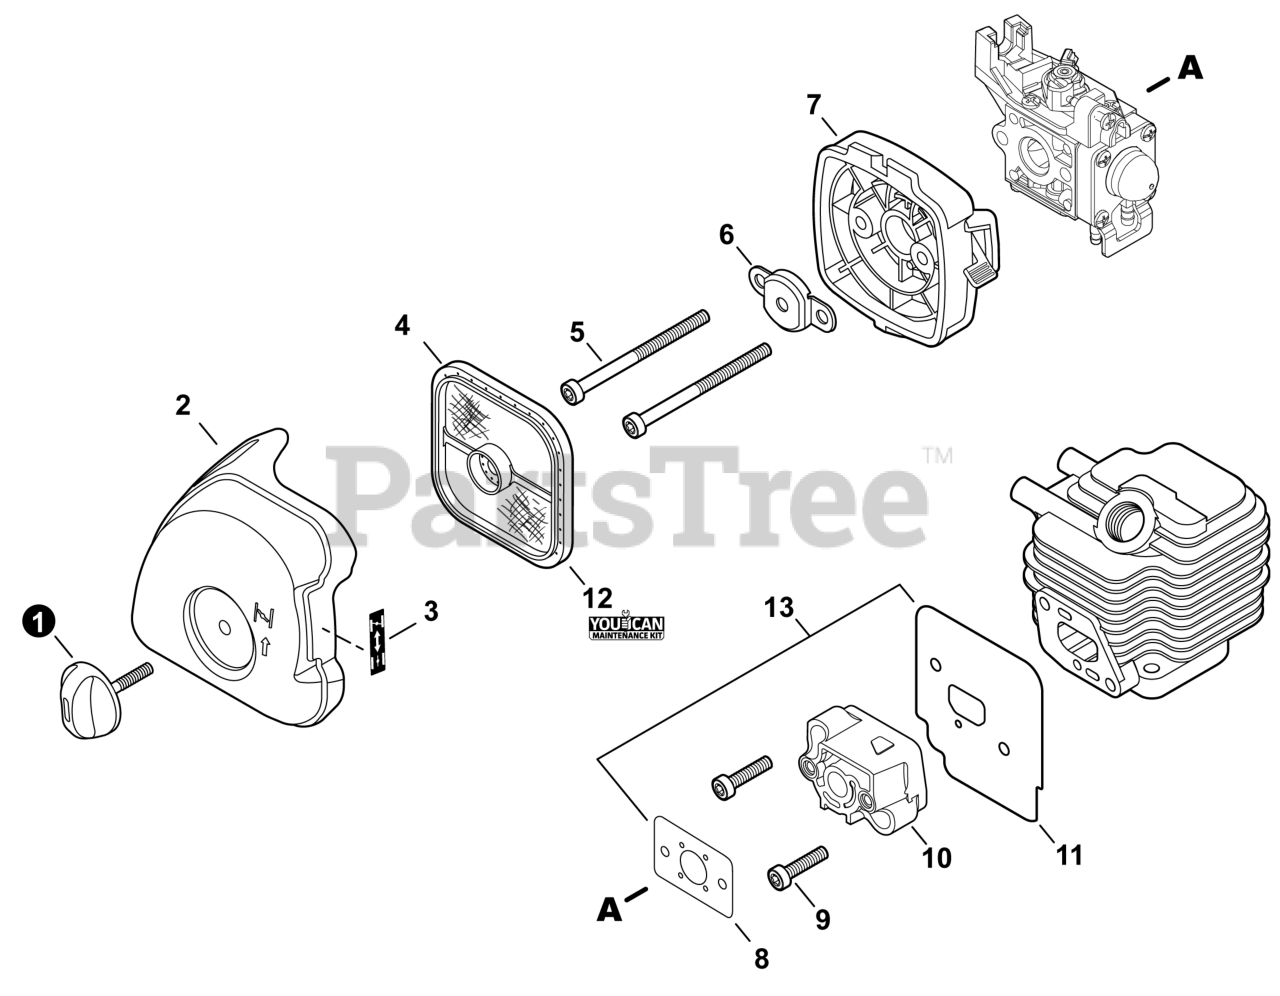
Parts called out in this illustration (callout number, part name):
1	THUMBSCREW
2	COVER, AIR FILTER
3	LABEL - CHOKE
4	FILTER, AIR - DOUBLE LAYER
5	BOLT, TORX 5x55
6	PLATE, PREVENT
7	CASE, AIR FILTER
8	GASKET, INTAKE
9	BOLT, TORX 5x20
10	INSULATOR, INTAKE
11	HEAT SHIELD, INTAKE
12	TUNE-UP KIT - YOUCAN™
13	GASKET KIT: ENGINE, INTAKE, EXHAUST
